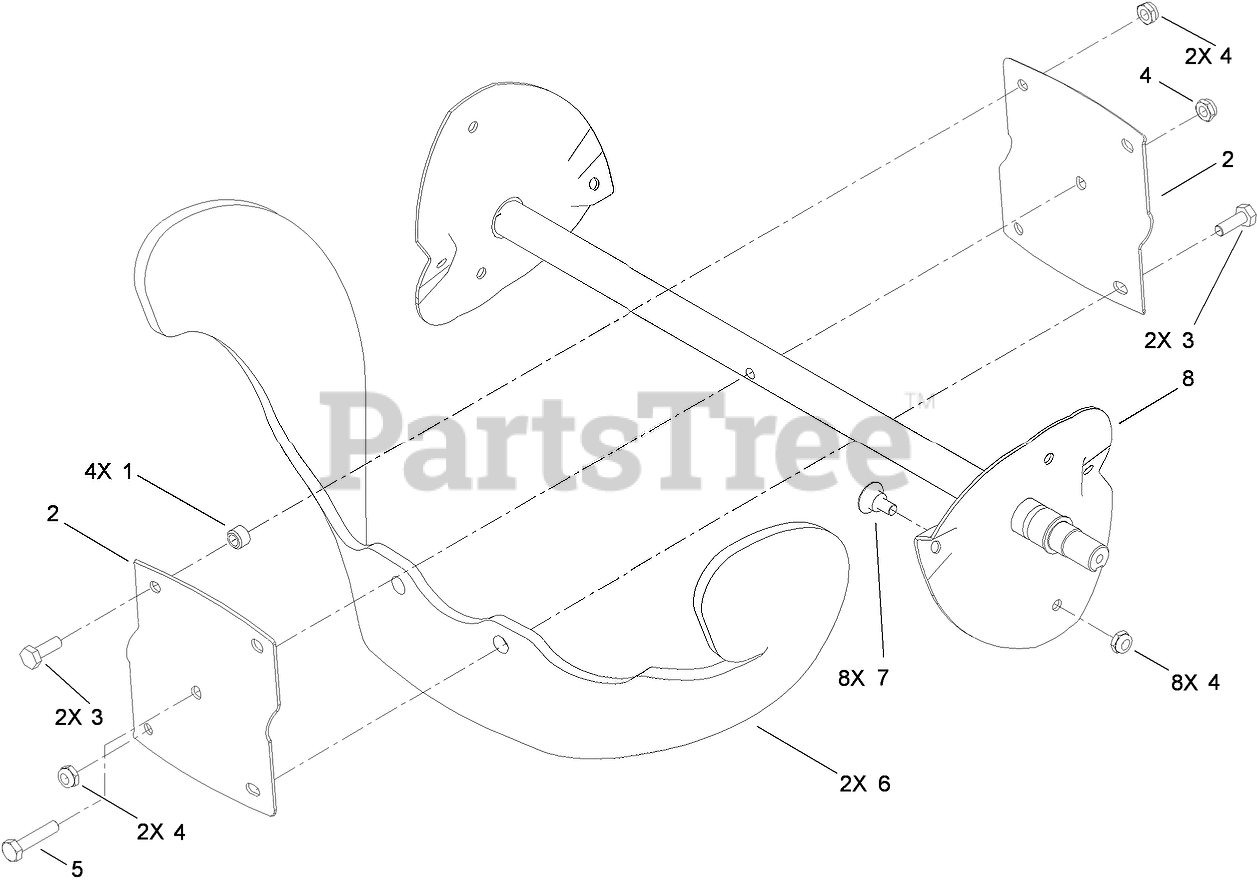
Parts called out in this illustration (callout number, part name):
1	SPACER-BLADE, ROTOR
2	HALF-ROTOR
3	SCREW-HH
4	NUT-LOCK, NI
5	SCREW-HH
6	BLADE-ROTOR
7	SCREW
8	ROTOR
